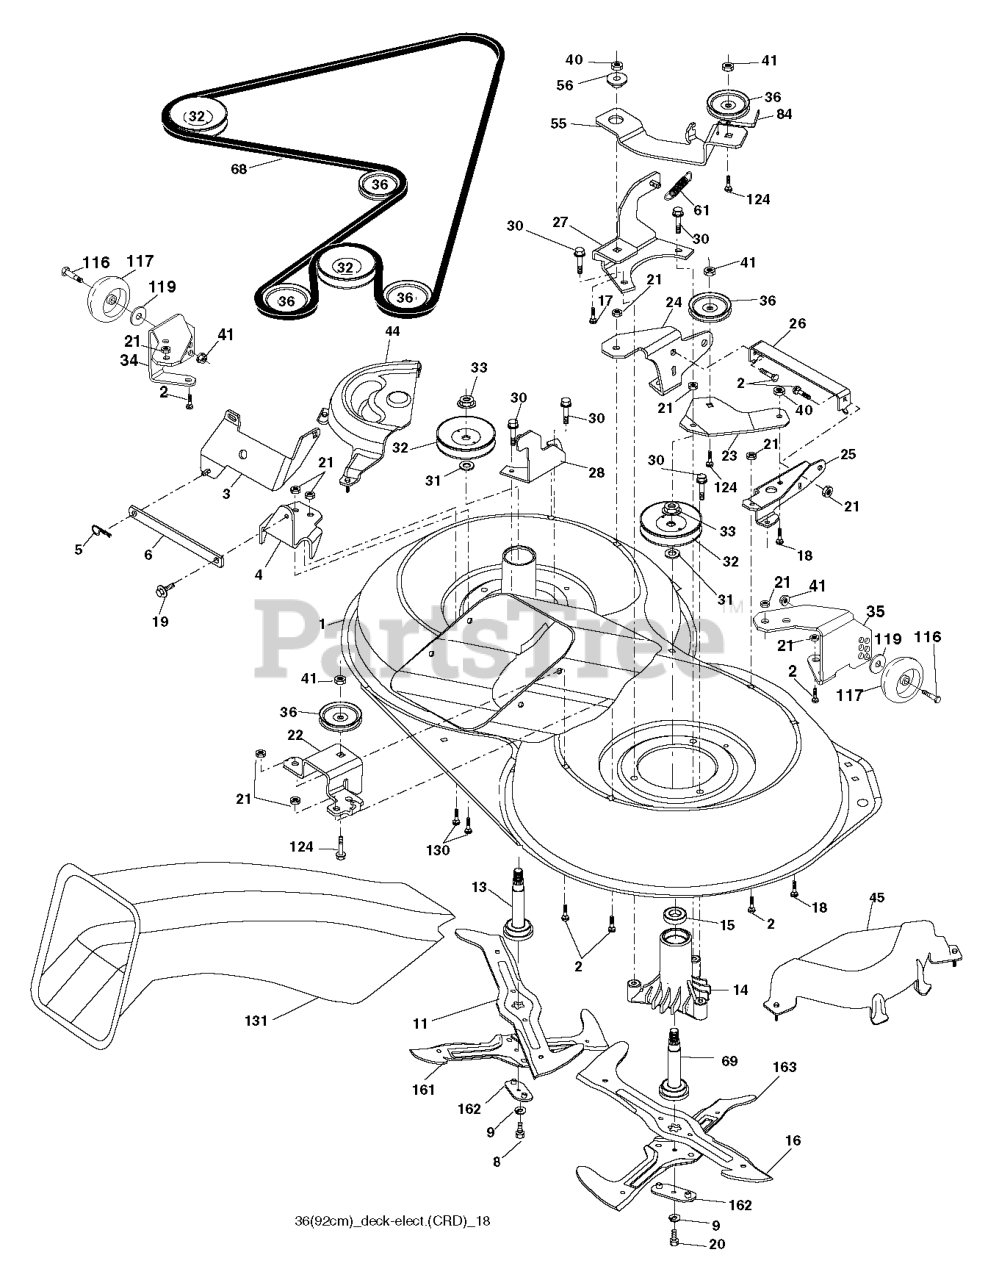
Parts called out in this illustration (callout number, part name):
2	RP BOLT 5/16-18 X3/4 ZN/YEL GR
3	BRACKET.ASM.BAR.SWAY.CHASS
5	RETAINER-SPRNG RB
6	BAR.SWAY.92.CRD
8	BOLT.3/8-24X1.25 GR8
9	LOCKWASHER
13	SHAFT ASM VENT
14	HOUSING.MANDREL.VENTED (MACHD)
17	BOLT.3/8-14X1.25
19	BOLT SHD 5/16-18
20	BOLT.3/8-24X1.25GR8. LHTHRD
21	LOCKNUT
25	BRACKET.SUPT.IDLER.REAR.RH
26	SUPPORT
30	SCREW, WASHER HEAD
31	WASHER.SPACER.MANDREL
33	NUT.FLANGE.LOCK.TOP
36	PULLEY.IDLER.4.25
41	NUT LOCK FLG 3/8-16 UNC
55	ARM.IDLER.92 CRD.2006
56	SPACER.RETAINER.MOWER
61	SPRING
68	BELT.DRIVE.92CM.CRD.2006
69	SHAFT.ASM.W/LWR.BRG.RH.THREAD
84	KEEPER, BELT IDLER
116	BOLT.SHOULDER.3/8-16X3-5/8.
117	RP WHEEL. GUAGE RALLY
119	WASHER
124	BOLT.3/8-16X1.50
130	BOLT.CARR.SQNK.5/16-18UNC.X3/4
131	CHUTE BAGGER
